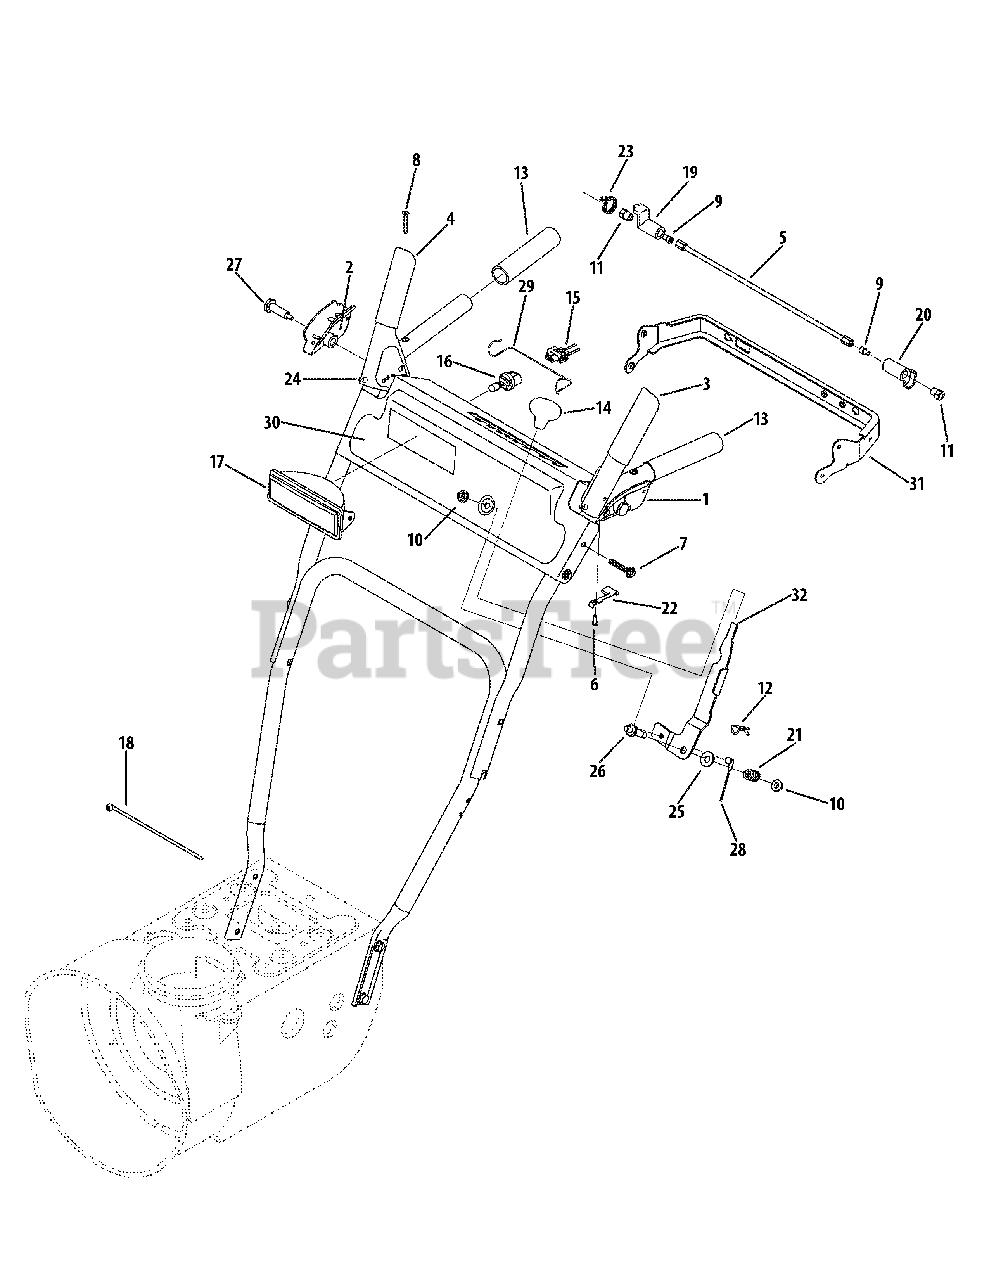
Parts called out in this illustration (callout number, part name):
1	Clutch Lock Handle Assembly, LH
2	Clutch Lock Handle Assembly, RH
3	Engagement Assembly, LH
4	Engagement Assembly, RH
5	Clutch Pivot Lock Rod Assembly
6	Hex Washer Screw, #8-16 x .50
7	Hex Washer Screw, 1/4-20 x .620
8	Machine Screw, #10-24 x 1.375
9	Socket Screw, 1/4-20 x .50
10	Flange Lock Nut, 5/16-18
11	Hex Nut, 1/4-20
12	Click Pin, .092 x 1.64
13	Grip, 1.0 ID x 5.0 LG
14	Shift Knob
15	Snow Thrower Harness
16	Halogen Lamp
17	Lens/Lamp Assembly Housing
18	Cable Tie
19	Lock Plate
20	Clutch Lock Cam
21	Compression Spring, .39 x .60 x .88
22	Clutch Lock Spring
23	Torsion Spring, .8156 ID x .3038
24	Rubber Bumper, .62 OD x .22 Thick
25	Flat Washer, .385 x .870 x .092
26	Shoulder Bolt, 5/16-18 x .905
27	Shoulder Screw, .437 x 1.345 x 1/4-20
28	Speed Selector Cable
29	Headlight Retainer
